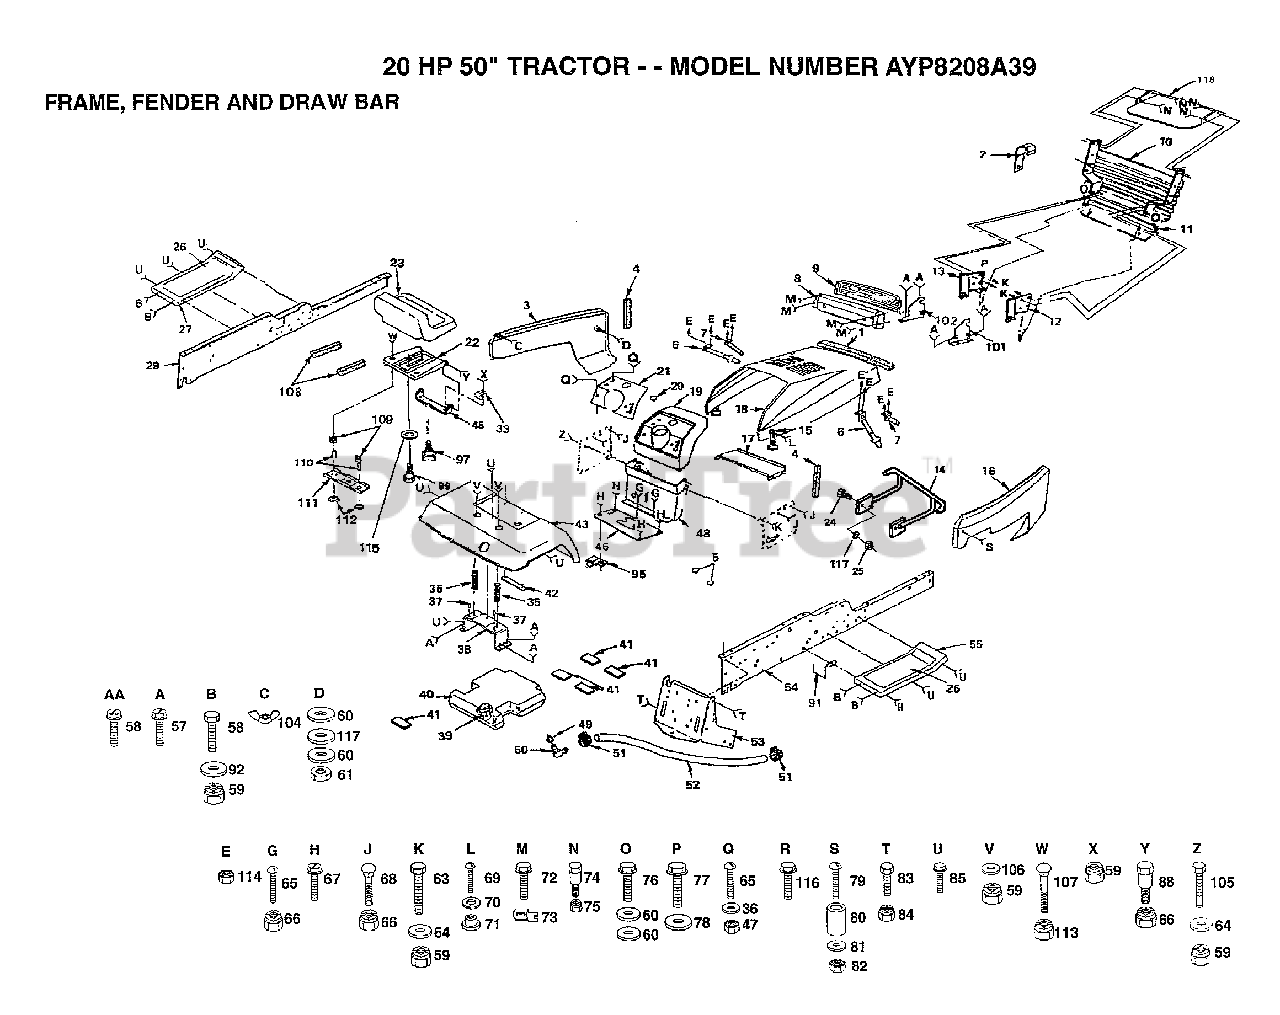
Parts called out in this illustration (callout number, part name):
1	FOAM STRIP T
3	"PANEL,SIDE LH "
4	FOAM STRIP T
5	CAP SPRING
9	LENS LT
12	SUPPORT RH YTH
13	SUPPORT LH YTH
14	BUMPER ASSY.
15	HOOD LATCH T
16	"PANEL,SIDE RH "
20	PLUG-DASH T
24	BOLT
26	FOOTREST PAD
33	CLIP T
35	SPRING COMPRESSIO
36	WASHER
37	NUT-PUSH YT
41	PAD-SPACER LT
43	FENDER
46	SADDLE.6SP.GT
48	DASH ASSEMBLY
49	BUSHING OUTLET T
50	STEM, TANK FUEL
51	HOSE CLAMP
57	SCREW
60	WASHER PM
63	BOLT
64	WASHER
65	SCREW
67	SCREW
68	BOLT
69	SCREW
70	LOCKWASHER
71	WELDNUT
73	"""J"" FASTENER LT"
76	SCREW
77	SCREW
78	WASHER
79	SCREW
80	SPACER LT
81	WASHER
83	BOLT
84	NUT GTV
85	SCREW LT
91	BELT RETAINER GT
92	WASHER
97	"KNOB 1/2"" YT"
99	"BOLT,SHOULDER"
101	SUPPORT RH YTH
102	SUPPORT LH YTH
106	WASHER
108	STRIP FORM
109	SPRING COMPRESSED
110	SPACER SPLIT
111	BRKT SWITCH
112	BUSHING
114	NUT
115	WASHER
116	SCREW GTV
117	WASHER
118	"SHIELD,HEAT"
